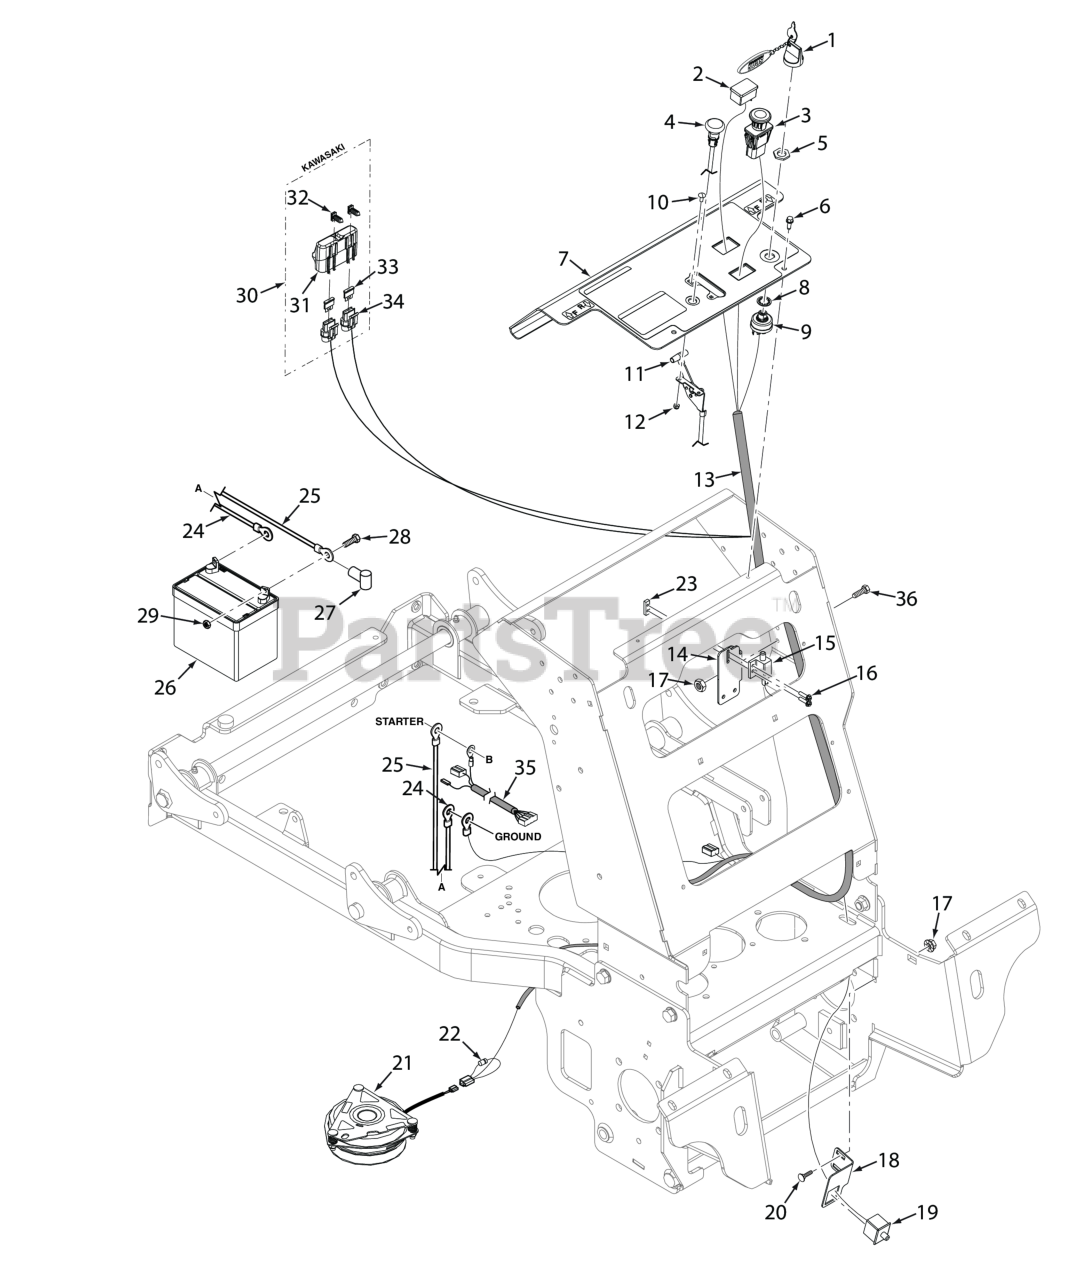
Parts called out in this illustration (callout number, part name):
1	Key, Assembly w/Fob
2	Hour Meter, Inductive
3	Switch, PTO - 10 Amp
4	Choke Control (excludes EFI models)
5	Nut, 5/8-32 Special
6	Screw, Self-Tapping 1/4-20 x 3/4
7	Instrument Panel w/Decal - SVRII36
8	LOCK WASHER, 5/8" INTERNAL TOOTH
9	KEY SWITCH(INCLUDES MOUNTING HARDWARE)
10	Bolt, Carriage #10-24 x 1/2"
11	Throttle Control, SVR
12	Nut, Elastic Stop #10-24
13	Wire Harness, SVRII-36
14	Bracket, Neutral Switch
15	Switch, Interlock (see below)
16	Screw, Hex-Slotted Washer Head #10 32 x 3/4"
17	NUT, 1/4-20 SERRATED FLANGE HEX HEAD
18	Switch Bracket, OPC Switch -SVRII-36
19	Switch, Double Pole OPC - SVRII-36
20	Serr. Fl. Hex Head CPSCR, 1/4-20 x 3/4"
21	Clutch w/Tag GT2.5-FE02 (48 / 52)
22	Diode, 600V 6 Amp
23	Plate, Threaded
24	Battery Cable, 39" Black (26EFI) - Kohler
25	Battery Cable, 44" Red w/Braid (26EFI) - Kohler
26	Battery, 350 CCA (not available through Scag)
27	RUBBER BOOT
28	BOLT, HEX HEAD, 1/4-20 X 3/4 GR.5
29	Nut, 1/4 - 20 Hex
30	Double Fuse Assy.
31	Cover, Sealed Double
32	Clip, Fuse Holder
33	FUSE, 20 AMP BLADE TYPE AUTOMOTIVE
34	Fuse Holder Assembly
35	Wire Harness Adapter, Kawasaki - 22FX & 23FX
36	BOLT, HEX HEAD, 1/4-20 X 3/4 GR.5
